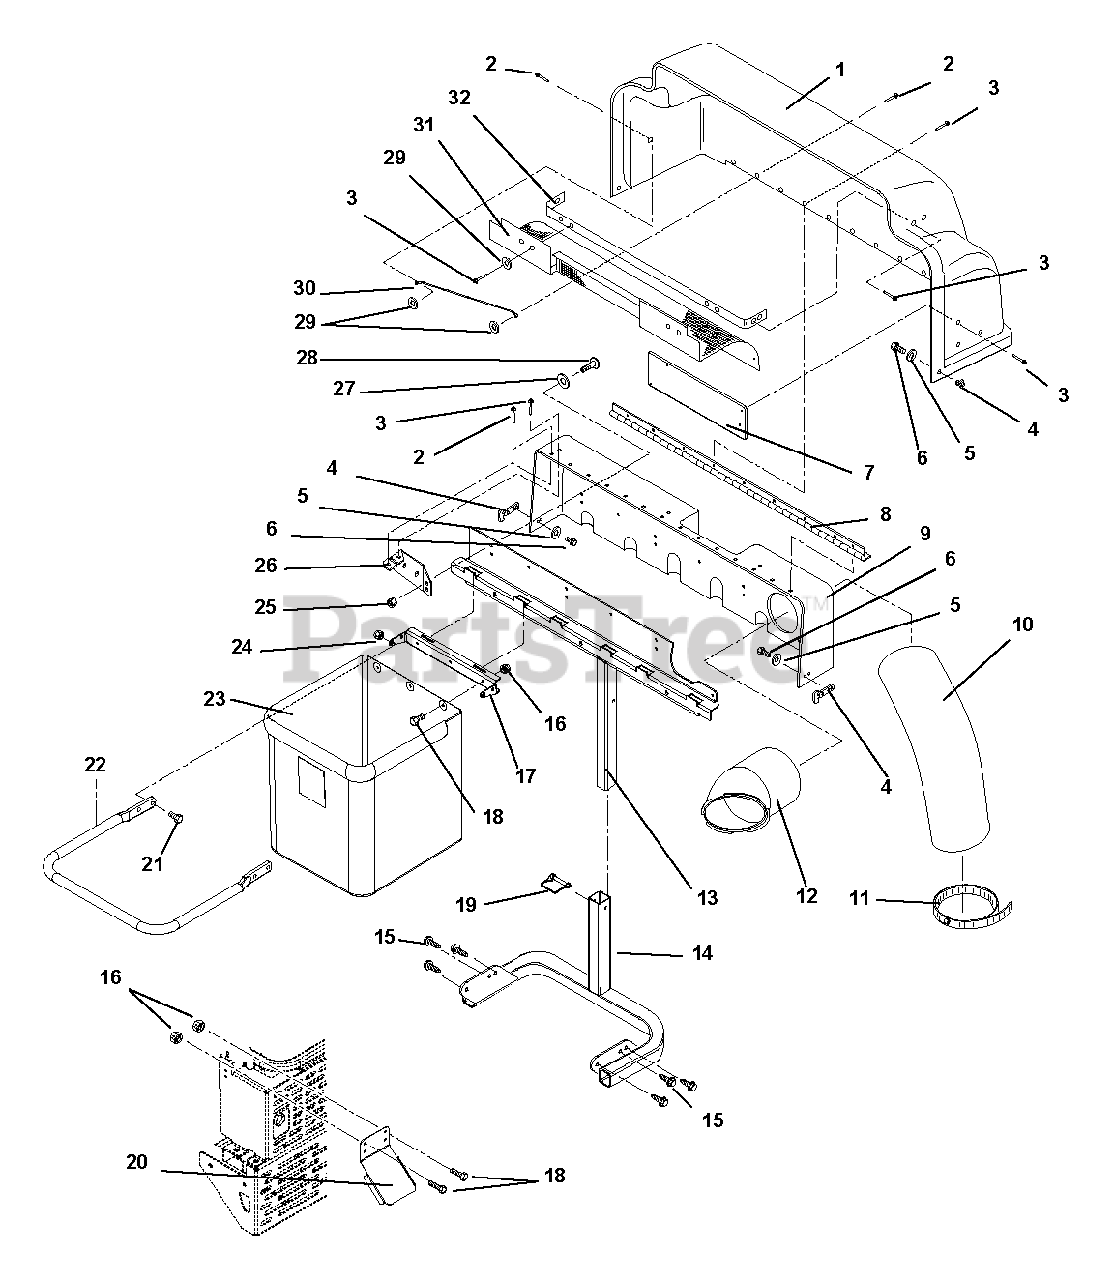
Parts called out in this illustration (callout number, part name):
1	Hinged Cover with Decal
2	Rivet-Pop .187 x .527
2	(Gravely Part Number)
3	Rivet-Pop .187 x .402
4	Latch, Rubber
5	Washer-Flat-Steel .219 x .50 x .049
6	Screw-Machine 10-24 x .50 Hex Washer Head
9	Stationary Cover
9	(Gravely Part Number)
10	Hose 7 x 45
11	Clamp-Hose Worm 2.13/8.62 x .56
11	(Gravely Part Number)
12	Bagger Boot- Upper
12	(Gravely Part Number)
13	Weldment-Bagger Frame
14	Weldment-Bumper (892005)
14	Weldment-Bumper (892012)
14	Weldment-Bumper (892016)
15	Screw-Tapping, .38-16 x .75 (892012, 892016)
16	Nut-Locking-Center .25-20
17	Clamp-Bag
18	Bolt-Hex .25-20 x .50 Grade 5
19	Pin-.38 x 2.50 Square Lock
20	Deflector, Exhaust
21	Bolt-Round Head Square Short Neck .31-18 x .75 Grade 5
22	Frame-Bag Support
23	Bag-Mesh Assist Bagger
24	Nut-Spin Lock-Flange .312-18
25	Nut- Locking-Nylon .312-18 Grade 2
26	(Gravely Part Number)
27	Washer-Flat-Steel .344 x .063
28	Bolt-Hex .31-18 x 1.00 Grade 2
29	Washer-Flat-Steel .194 x .492 x .047
30	(Gravely Part Number)
32	Screen Mounting Bracket
